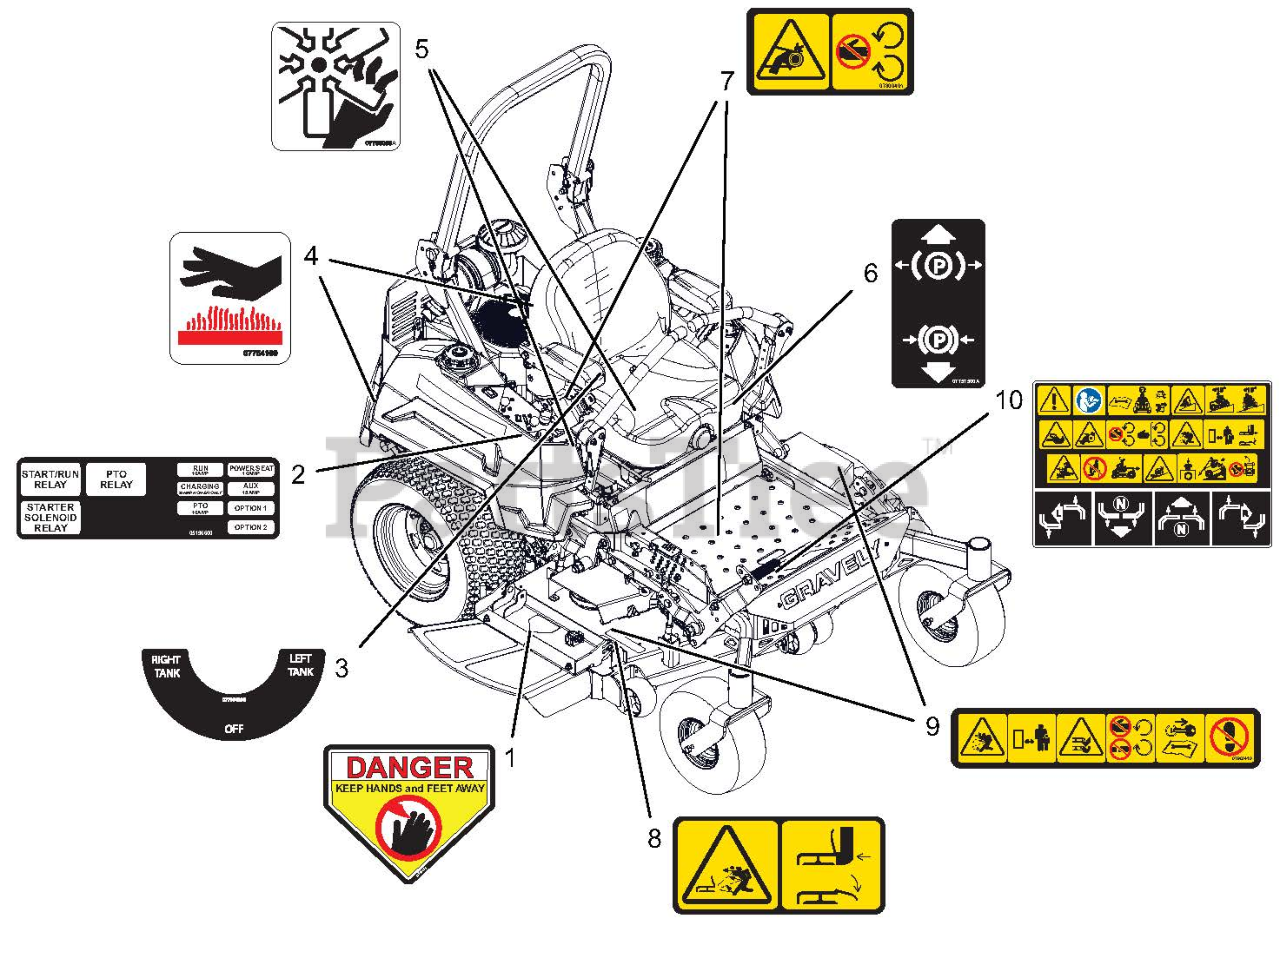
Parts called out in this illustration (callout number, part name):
1	DECAL, DANGER
2	DECAL, PT200/400 FUSE BOX
3	DECAL- FUEL CONTROL VALVE
4	DECAL, HOT SURFACE
5	DECAL, DANGER FAN
6	DECAL, PARKING BRAKE LEVER
7	DECAL, SAFETY - GUARDING
8	DECAL, SAFETY - DECK GUARDING
9	DECAL, DECK SAFETY
10	DECAL, INSTR SAFETY
